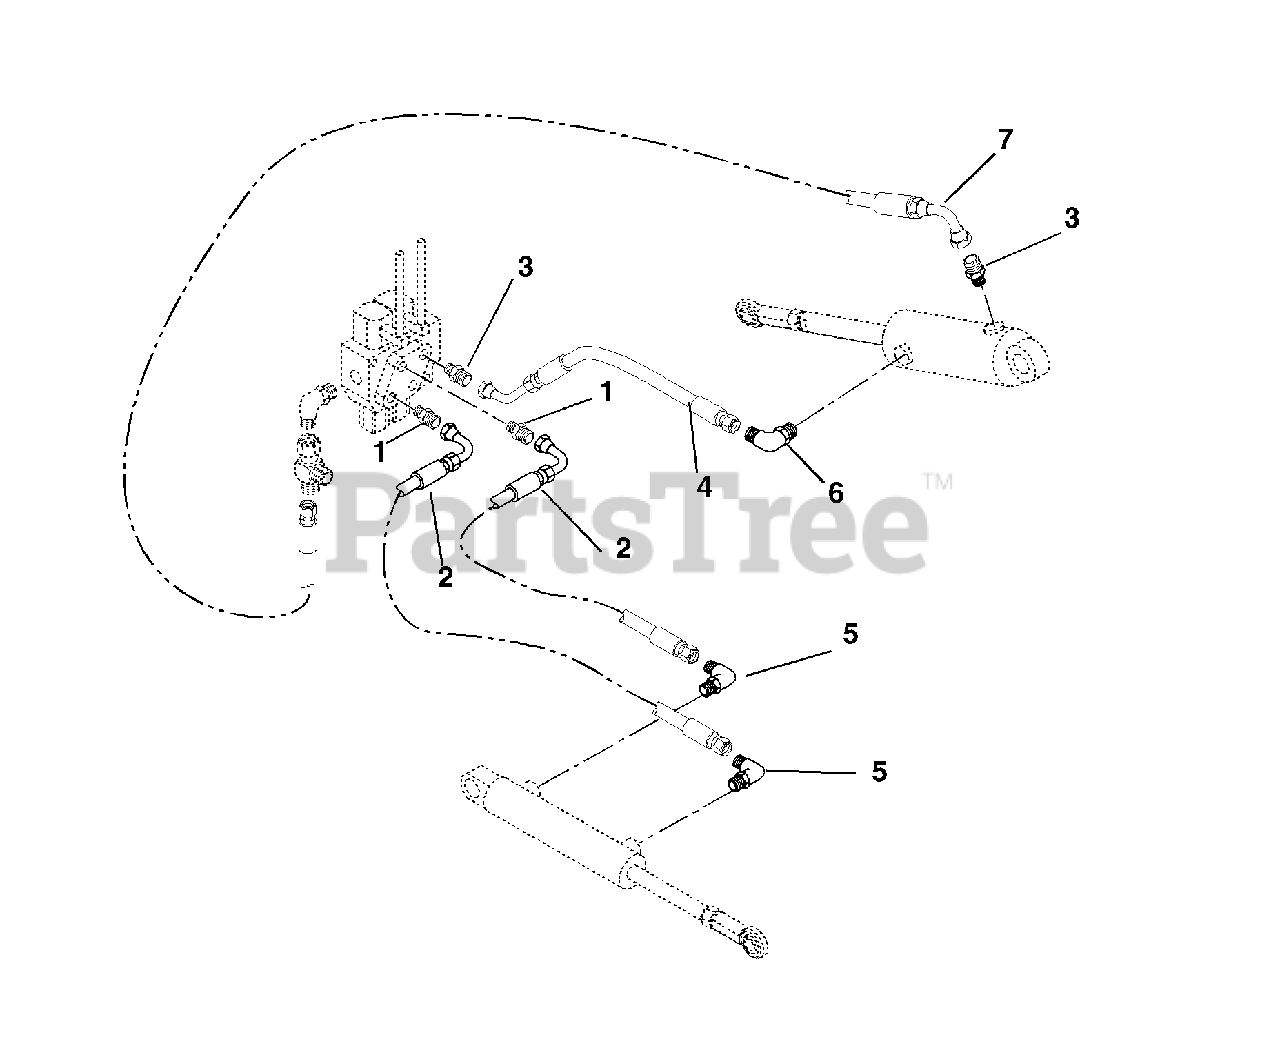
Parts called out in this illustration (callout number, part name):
1	Fitting, Hydraulic
2	Hose, Hydraulic
3	Fitting, Hydraulic
4	Hose, Hydraulic
5	Fitting, Hydraulic
6	Fitting, Hydraulic
7	Hose, Hydraulic
